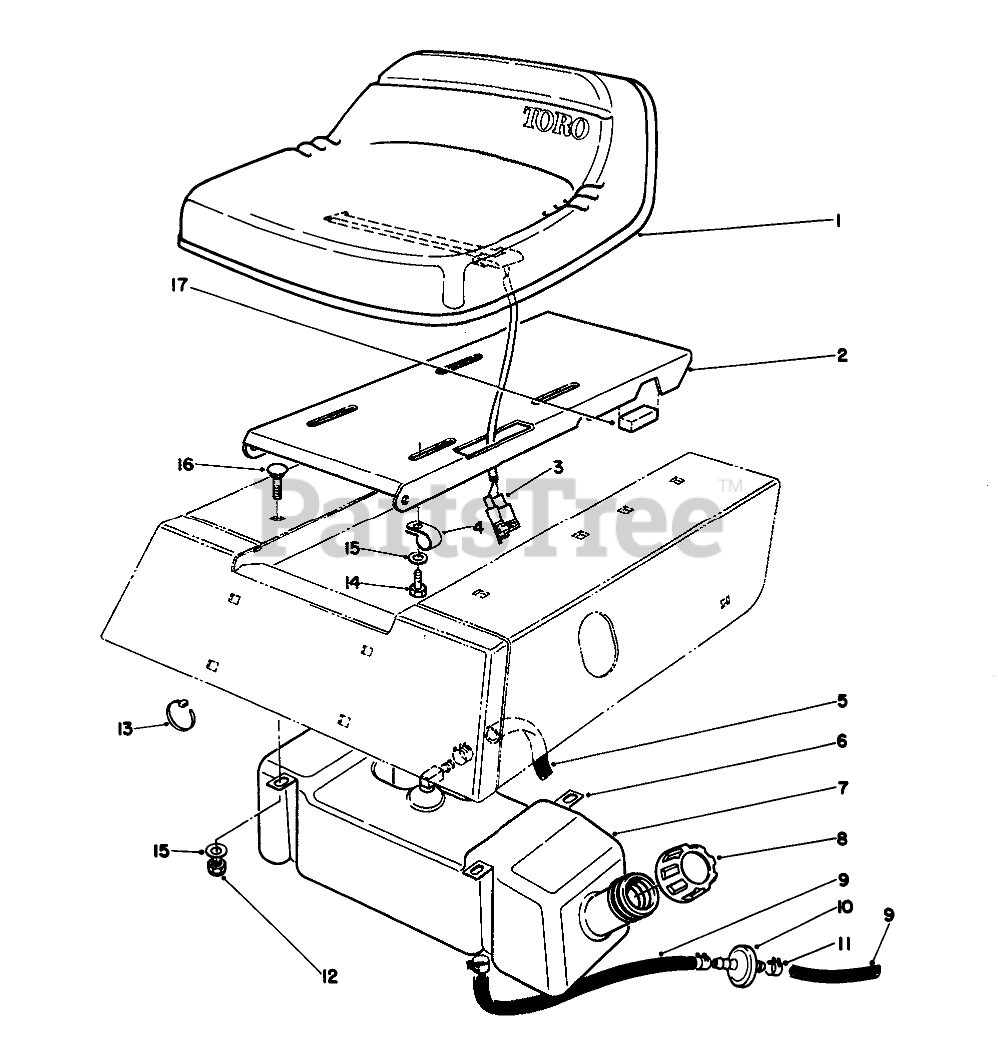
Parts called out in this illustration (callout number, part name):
1	Seat
2	BASE - SEAT
3	SWITCH-SEAT
4	CLIP-FUEL LINE
5	HOSE-FUEL
6	STRAP-GAS TANK
7	TANK-GAS
8	GAS CAP ASM
9	HOSE-FUEL
10	FILTER-FUEL
11	CLAMP-HOSE
12	NUT-LOCK, NI
13	TIE-CABLE
14	SCREW-HH
15	WASHER-PLAIN
16	SCREW-CARR
17	PAD-ISOLATOR
